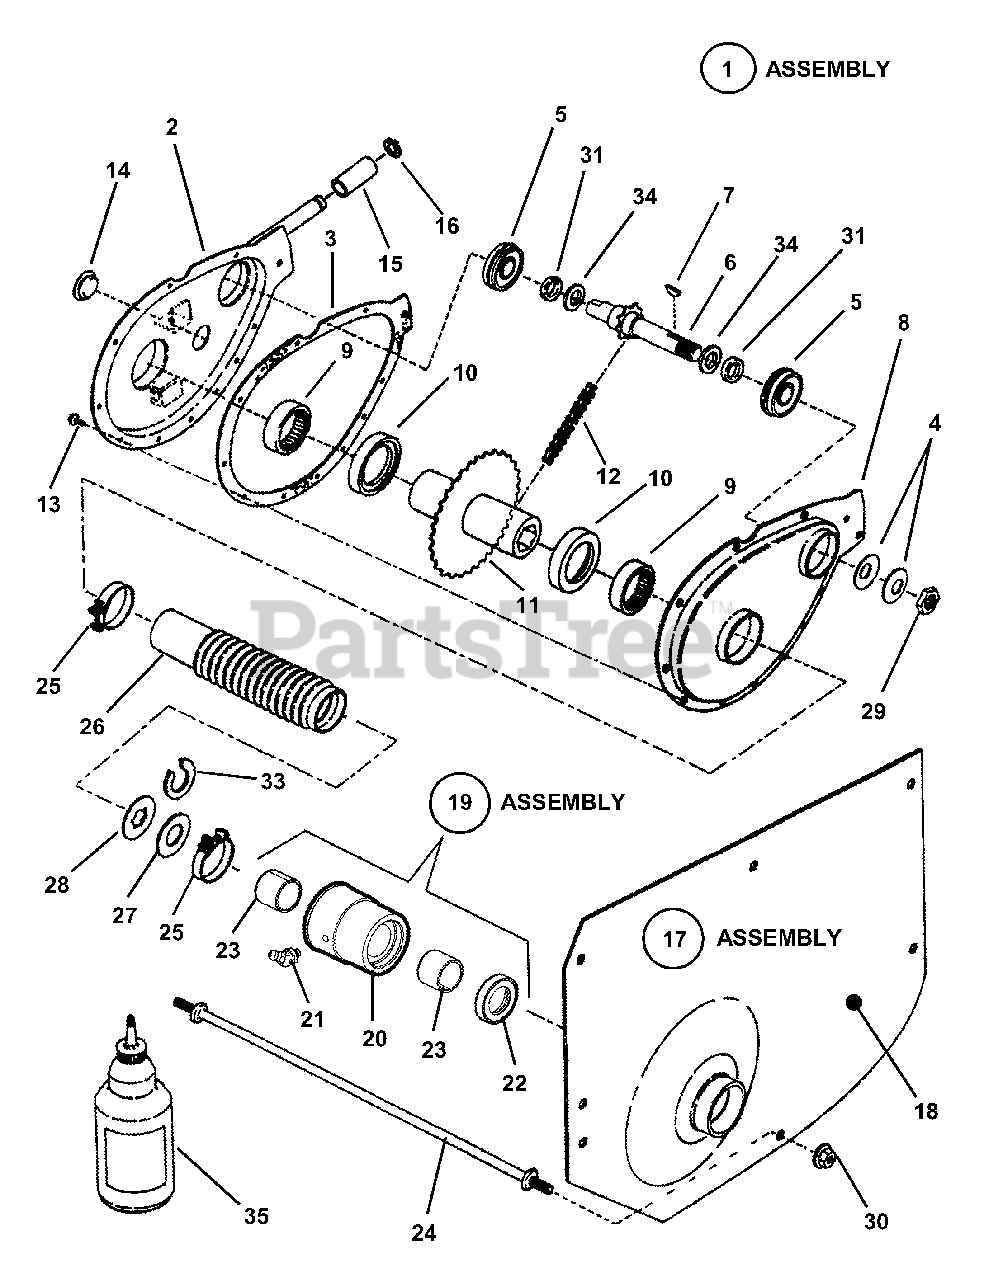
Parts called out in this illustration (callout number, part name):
1	ASSEMBLY, Chain Case
2	CASE, Sprocket
3	GASKET, Case Cover
4	WASHER, .640 I.D. Belleville
5	BEARING, Ball
6	SPROCKET & SHAFT
7	KEY, 1/8 x 5/8" Woodruff
8	COVER, Chain Case
9	BEARING, Needle
10	WASHER, Nylon Thrust
11	HUB & SPROCKET
12	CHAIN
13	SCREW, #10-24 x 1/2" Hex Washer Self-Tap (Torx)
14	PLUG, Oil Fill & Check
15	ROLLER
16	RING, 1/2" Heavy Duty External Retaining
17	ASSEMBLY, L. H. Fender & Bearing
18	FENDER, Left Hand (1.628" I.D. hole)
19	ASSEMBLY, Axle Bearing
20	BEARING, Axle
21	FITTING, Lube
22	SEAL, Dust/Grease Axle
23	BEARING, DX
24	ROD, Cross-Tie
25	CLAMP, Boot
26	BOOT, Oil Seal
27	WASHER, Thrust Nylon
28	WASHER, Thrust
29	NUT, 5/8-18 Hex Nyloc
30	NUT, 5/16-24 Hex Flange Lock
31	O-RING
33	WASHER, Shim
34	WASHER, Shim
35	GREASE, Transmission
